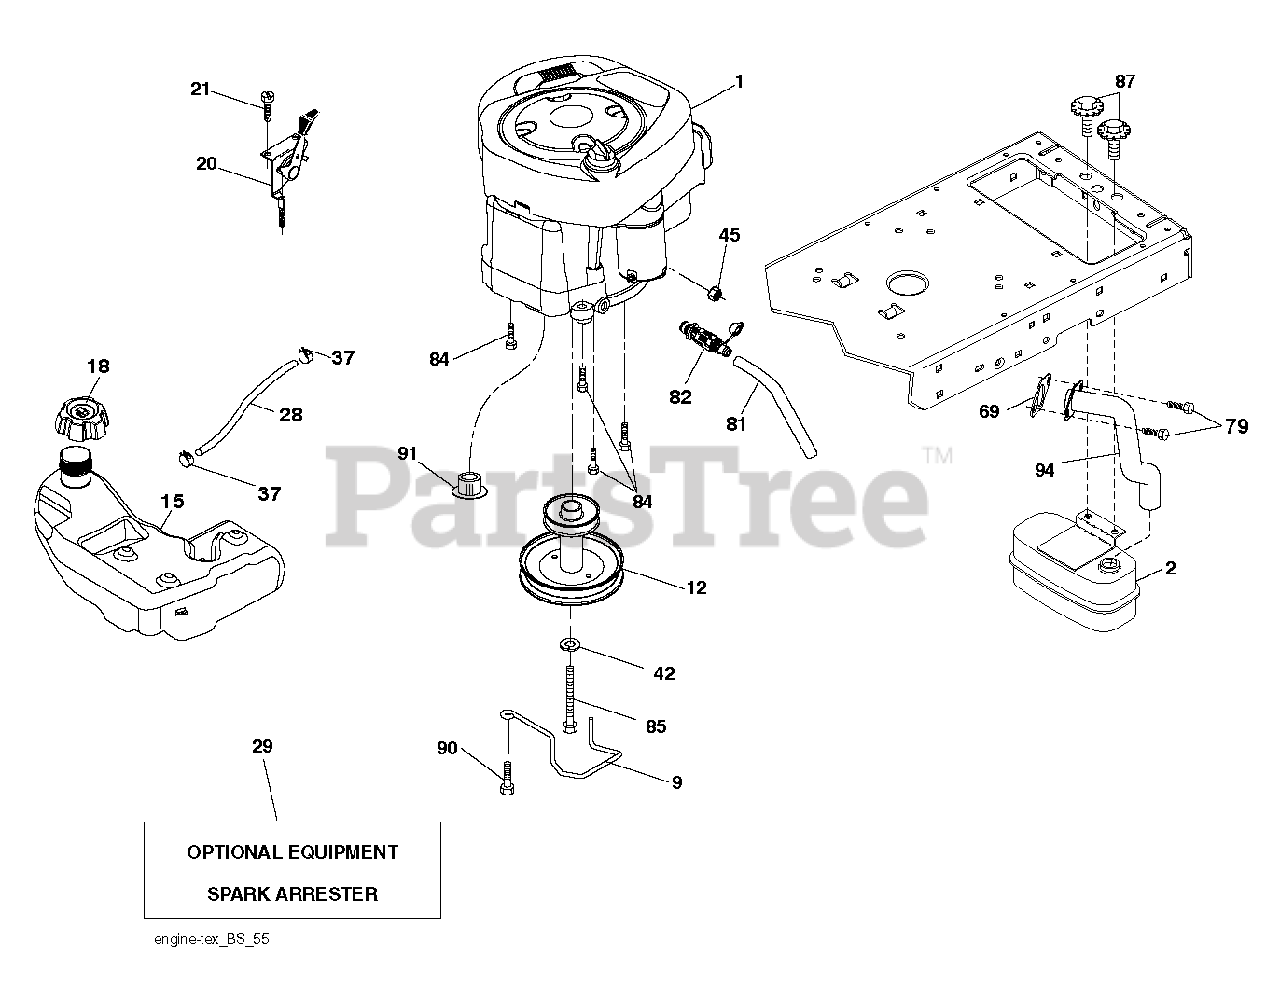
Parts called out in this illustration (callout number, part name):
2	MUFFLER.SINGLE.LRG.BRIGGS.KOHL
9	KEEPER.BELT.ENGINE.4.2
12	PULLEY ENGINE
15	TANK.ASSY.3.GAL.EPA
18	CAP.ASM.FL.RITCH.3"E10.SYM.498
20	CONTROL.TH/CK.COBRA.KO
21	SCREW.#10 X 0.750.BOS
28	LINE.FUEL.20"FRONT.EMI
29	KIT.SPARK ARRESTOR 794945 B&S
37	HOSE CLAMP
42	LOCKWASHER
45	NUT
69	REPL BY 532 27 22-93
79	SCREW.SOCKET HD.5/16-1
81	TUBE, DRAIN OIL ASM.
82	VALUE.OIL.DRAIN
84	SCREW.3/8-16
85	BOLT HEX 7/16-20X4-1/4"
87	Bolt, 5/16-18 X 1-3/4
90	SCREW 3/8-16X1
91	BUSHING.1.375OD
94	RP.EXHAUST.TUBE.B&S.28/31
